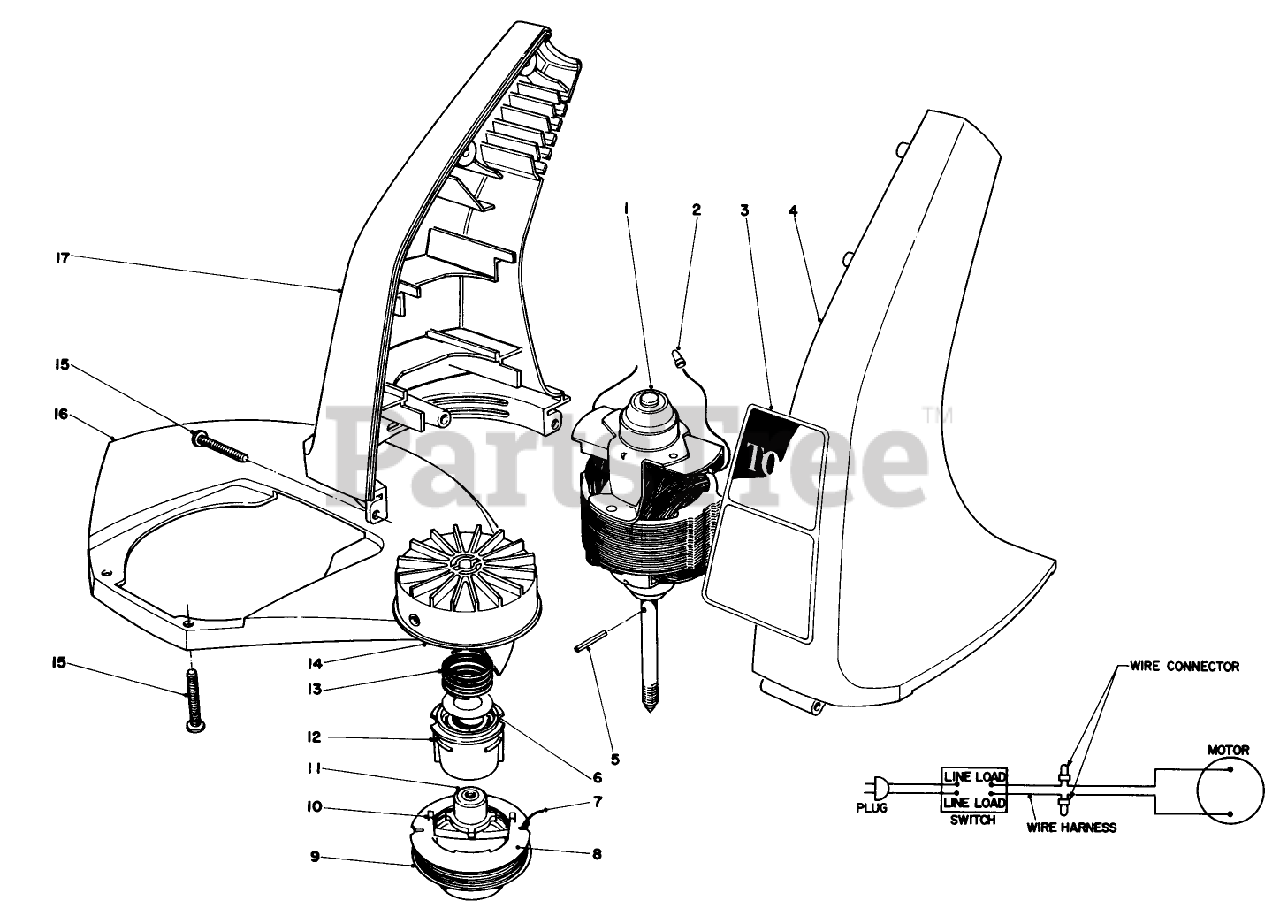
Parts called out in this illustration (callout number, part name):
1	Motor
2	CONNECTOR WIRE JOINT
3	DECAL - 1100 CANADIAN
4	Housing-Left Hand
5	COIL PIN
6	WASHER-FLAT
7	LINE-FILIMENT
8	Empty SPooI
9	Cutting Line (50 .065" Dia.)
10	SADDLE-SPOOL CAP
11	Driver
12	SPOOL CORE
13	SPRING COMPRESSION
14	DRUM W/EYELET
15	Screw
16	Shield
17	R.H. HOUSING, 1100
